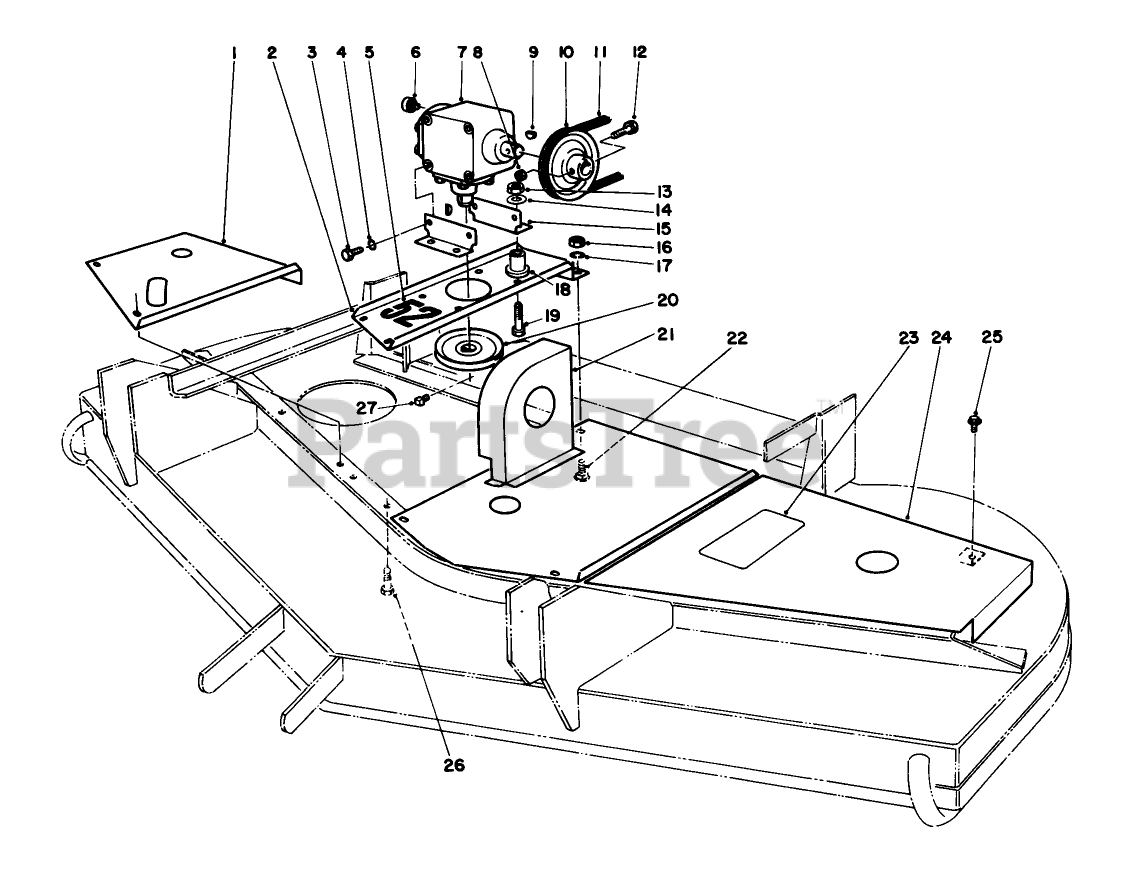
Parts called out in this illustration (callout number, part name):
3	SCREW-HH
4	WASHER-LOCK
5	DECAL
6	FITTING-LUBE
8	NUT-LOCK, NI
10	PULLEY
11	V-BELT, DECK
12	SCREW-HH
13	NUT-LOCK, SIDE
14	WASHER
16	NUT-LOCK, NI
17	WASHER-LOCK
18	MOUNT
19	SCREW-HH
20	PULLEY
22	BOLT-CARR
25	SCREW-HHFTF
26	SCREW-HH
27	SCREW-SET, SQH
